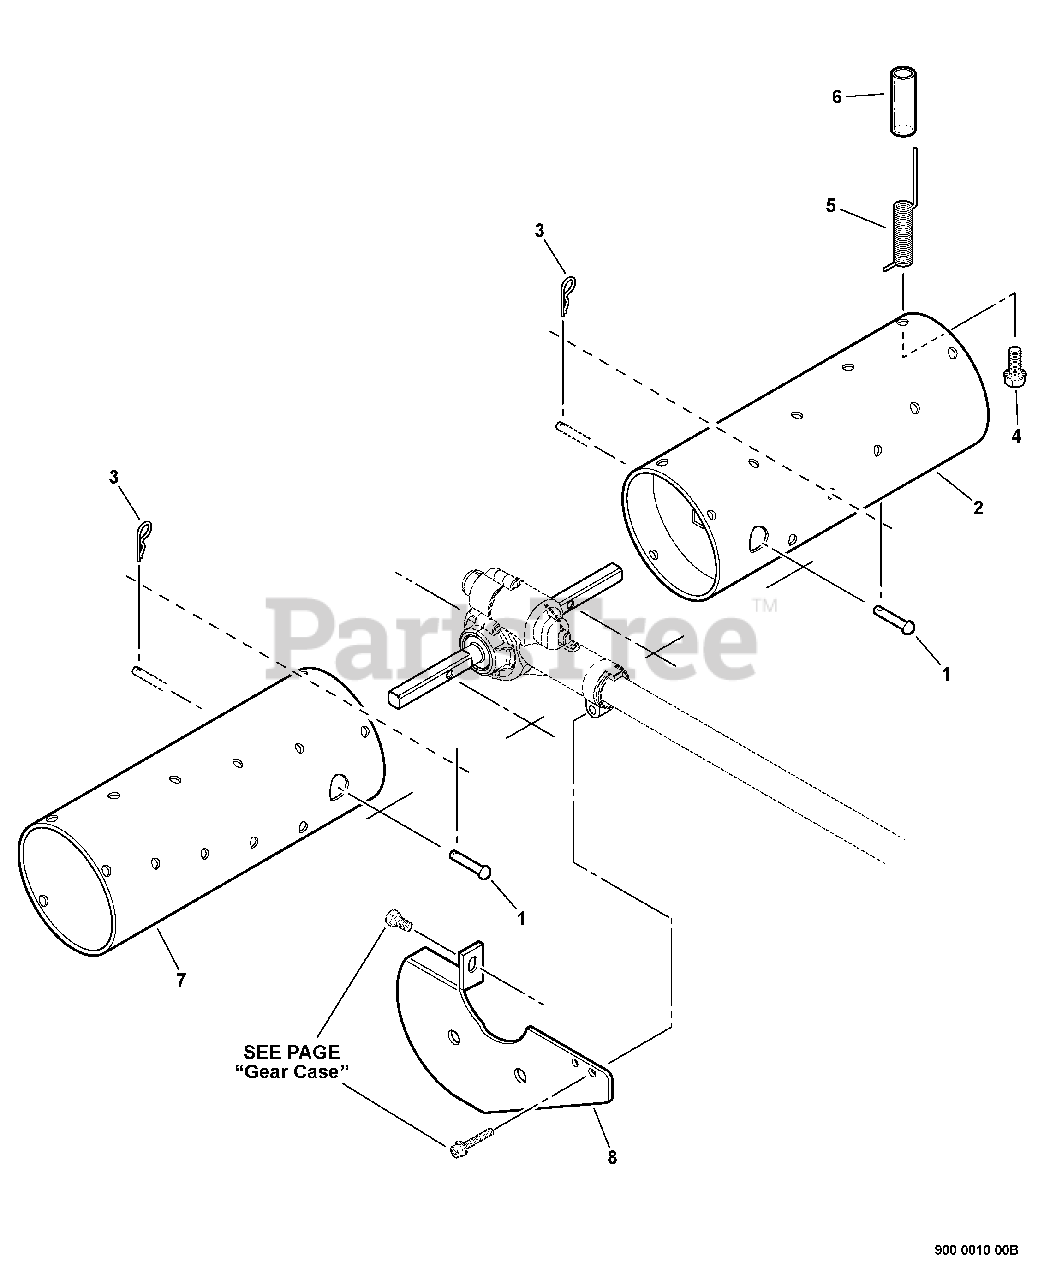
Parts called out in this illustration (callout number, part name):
1	PIN - CLEVIS
2	DRUM - RIGHT
3	PIN, SPLIT
4	BOLT - 6
5	SPRING, THATCHING
6	COVER, DEBRIS
7	DRUM - LEFT
8	GUIDE, GRASS
